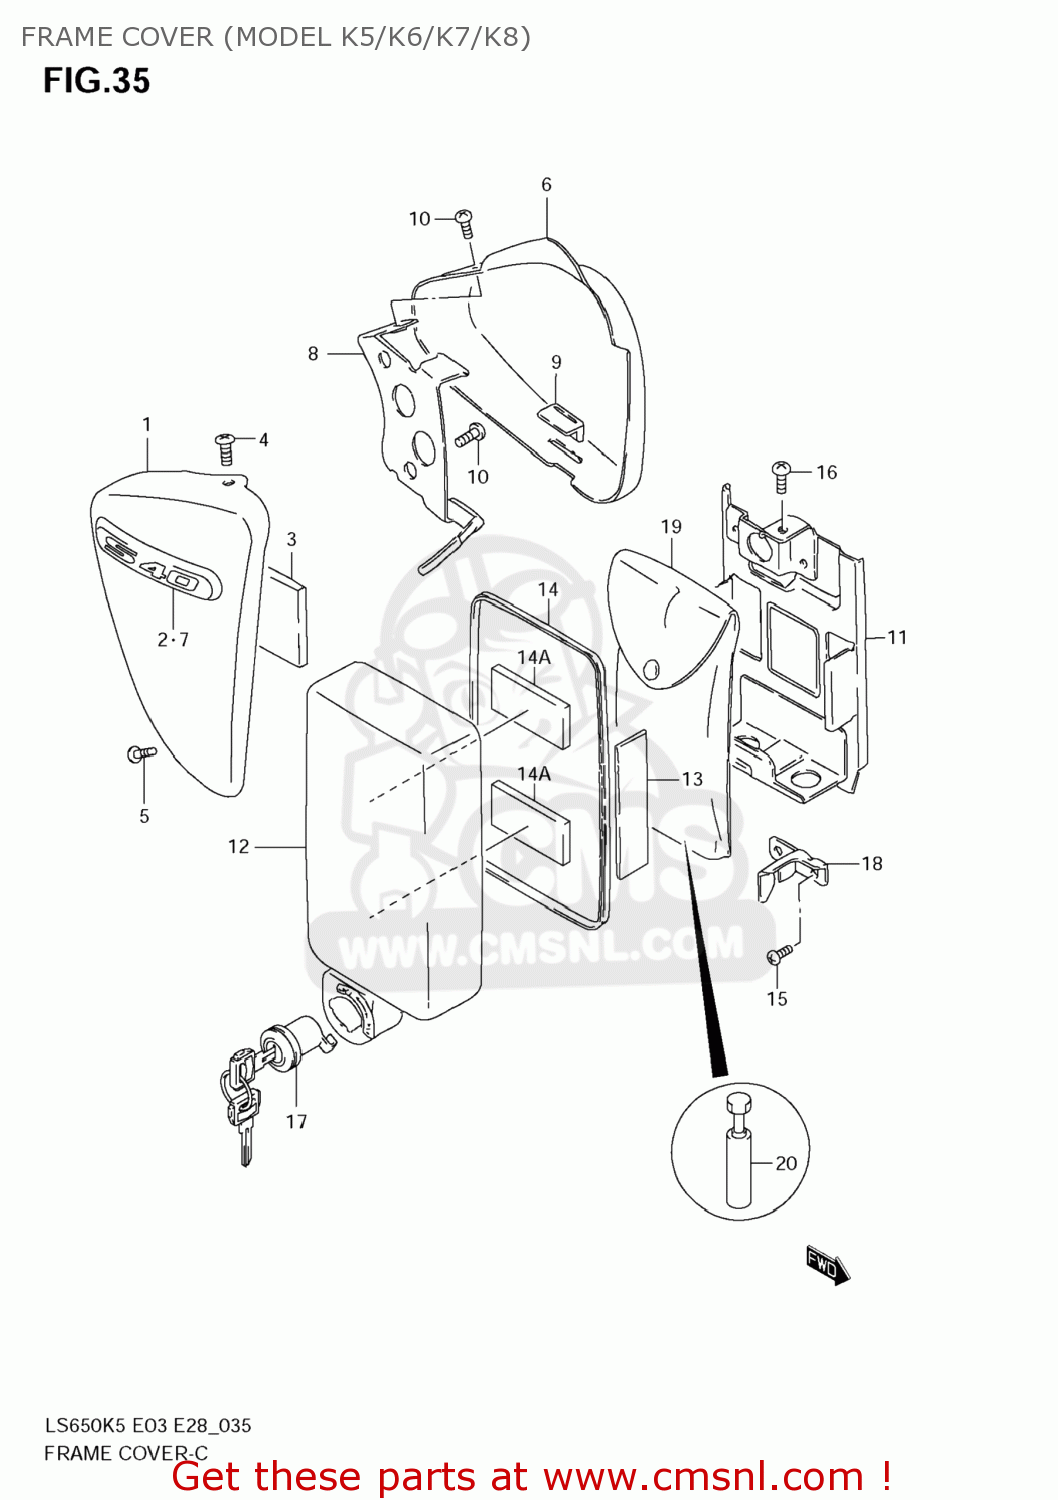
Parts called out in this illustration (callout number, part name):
1	COVER, FRAME RH (WHITE)
2	EMBLEM,FRAME COVER
3	PAD
4	SCREW
5	SCREW
6	COVER ASSY,FRAME,L(WHITE)
7	EMBLEM,FRAME COVER
8	BRACKET,FRAME COVER,L
9	CUSHION,FRAME COVER
10	SCREW
11	HOLDER,TOOL
12	COVER,TOOL HOLDER
13	PROTECTOR(20X90)X2
14	MOLDING
14A	PROTECTOR(20X50X11)
15	SCREW
16	SCREW, CENTER SHAFT
17	LOCK SET,TOOL HOLDER
18	PLATE,TOOL HOLDER LOCK
19	TOOL ASSY
20	GAUGE ASSY,TENSION
